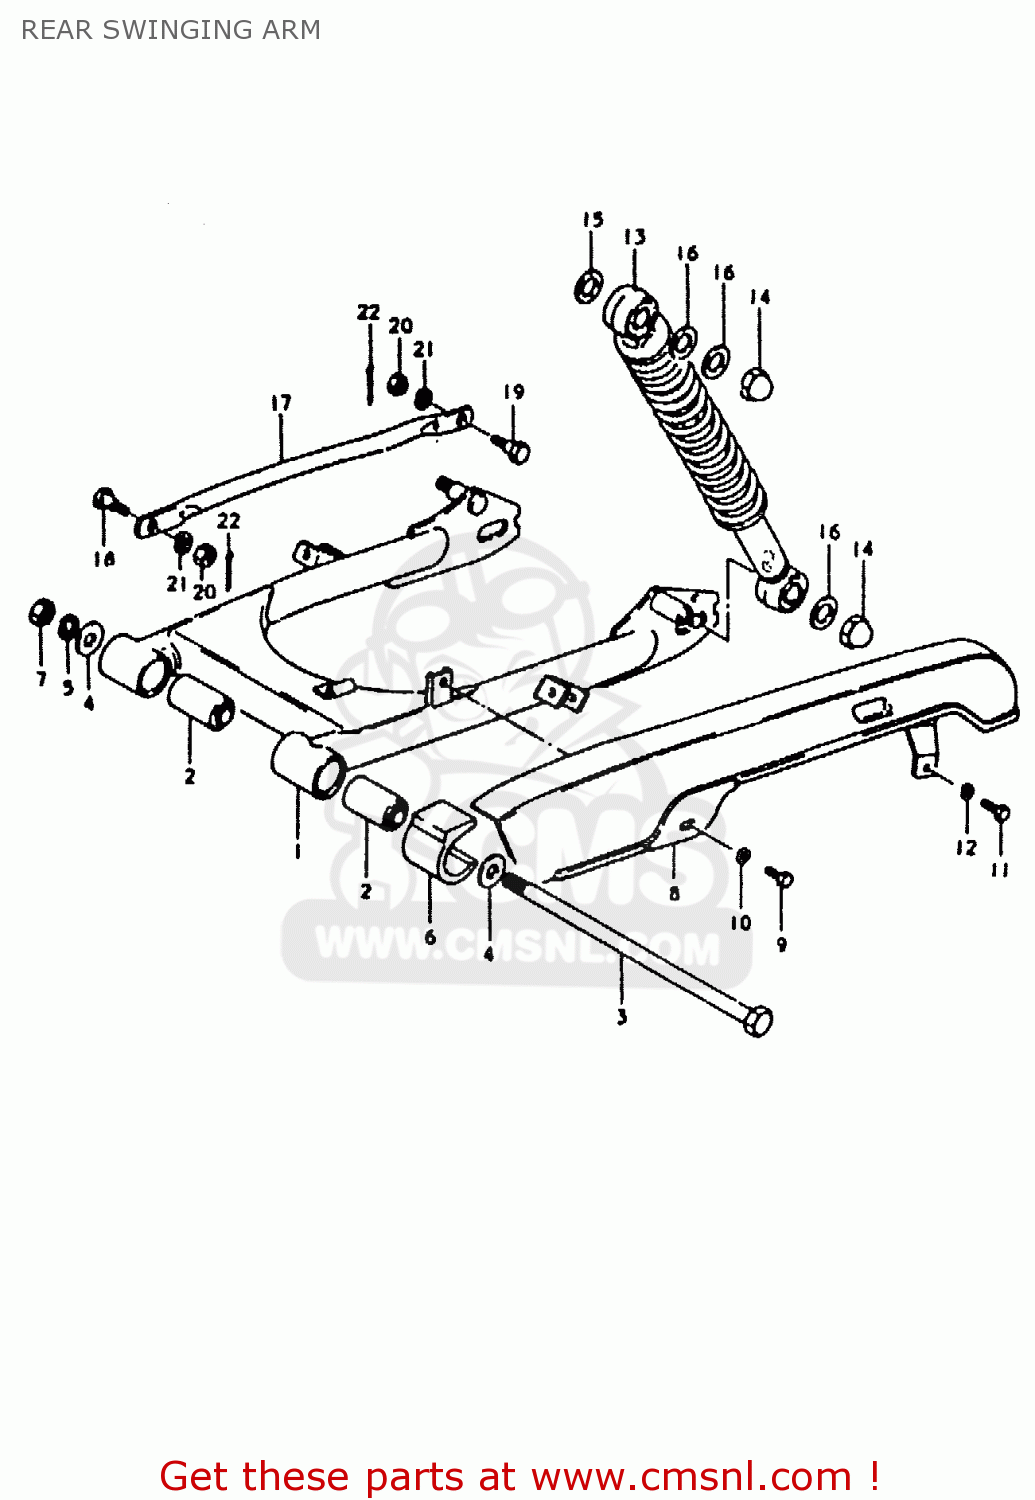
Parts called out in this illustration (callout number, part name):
1	SWINGING ARM SET (BLACK)
2	BUSH
3	SHAFT,RR SHOCK ABSORBER UPR
4	WASHER
5	LOCK WASHER
6	BUFFER,CHAIN TOUCH DEFENSE
7	NUT
8	CHAIN CASE
9	BOLT
10	LOCK WASHER
11	BOLT, UPPER
12	LOCK WASHER
13	SHOCK ABSORBER, REAR
14	NUT
15	WASHER
16	WASHER
17	TORQUE LINK, REAR
18	BOLT(8X22)
19	BOLT(8X26.5)
20	NUT
21	LOCK WASHER
22	PIN
